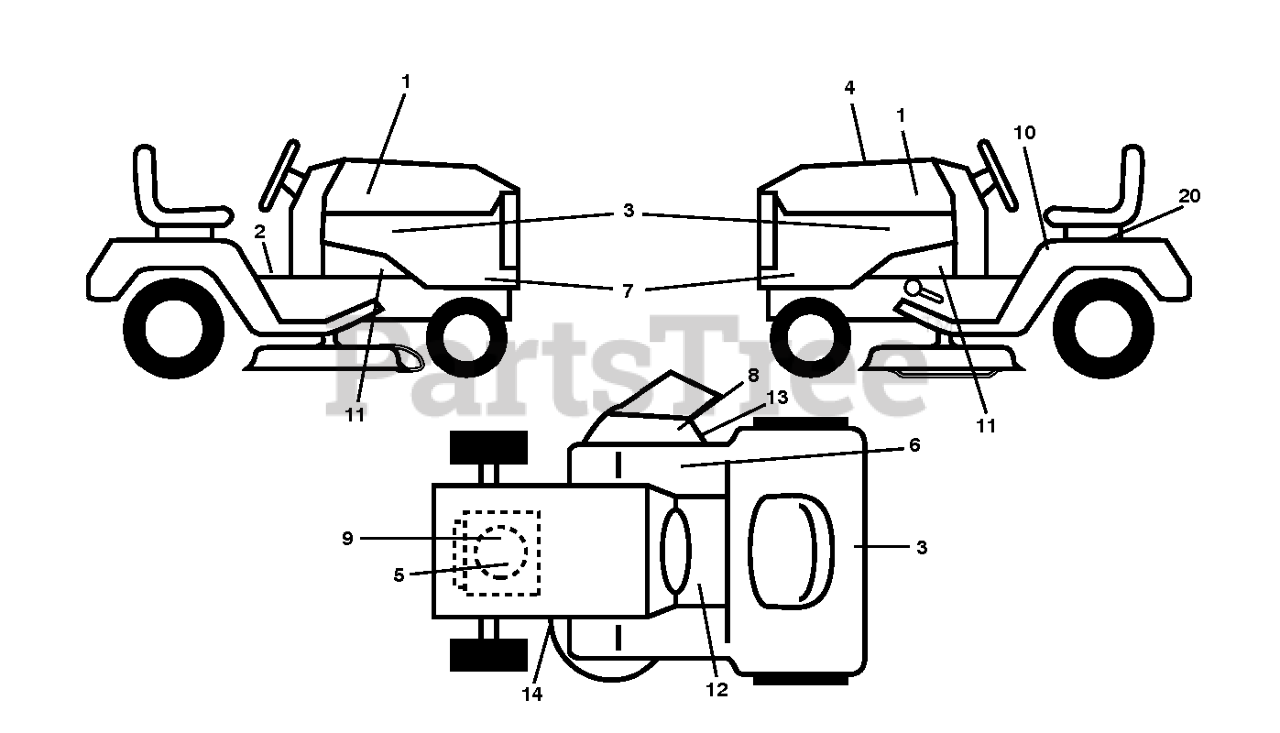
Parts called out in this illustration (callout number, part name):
2	DECAL PARK BRAKE
3	DECAL.HOOD.HUSQLOGO.ORANGE
5	DECAL
6	Decal, Fender 100 DB/CE
8	DECAL.INTERNATIONL.CUTFINGER
9	DECAL
10	LABEL
12	DECAL
13	DECAL, DEFLECT WARNING
14	DECAL.V-BELT.SCHEMATIC.36/38/9
20	DECAL BTRY SYMBOLS
